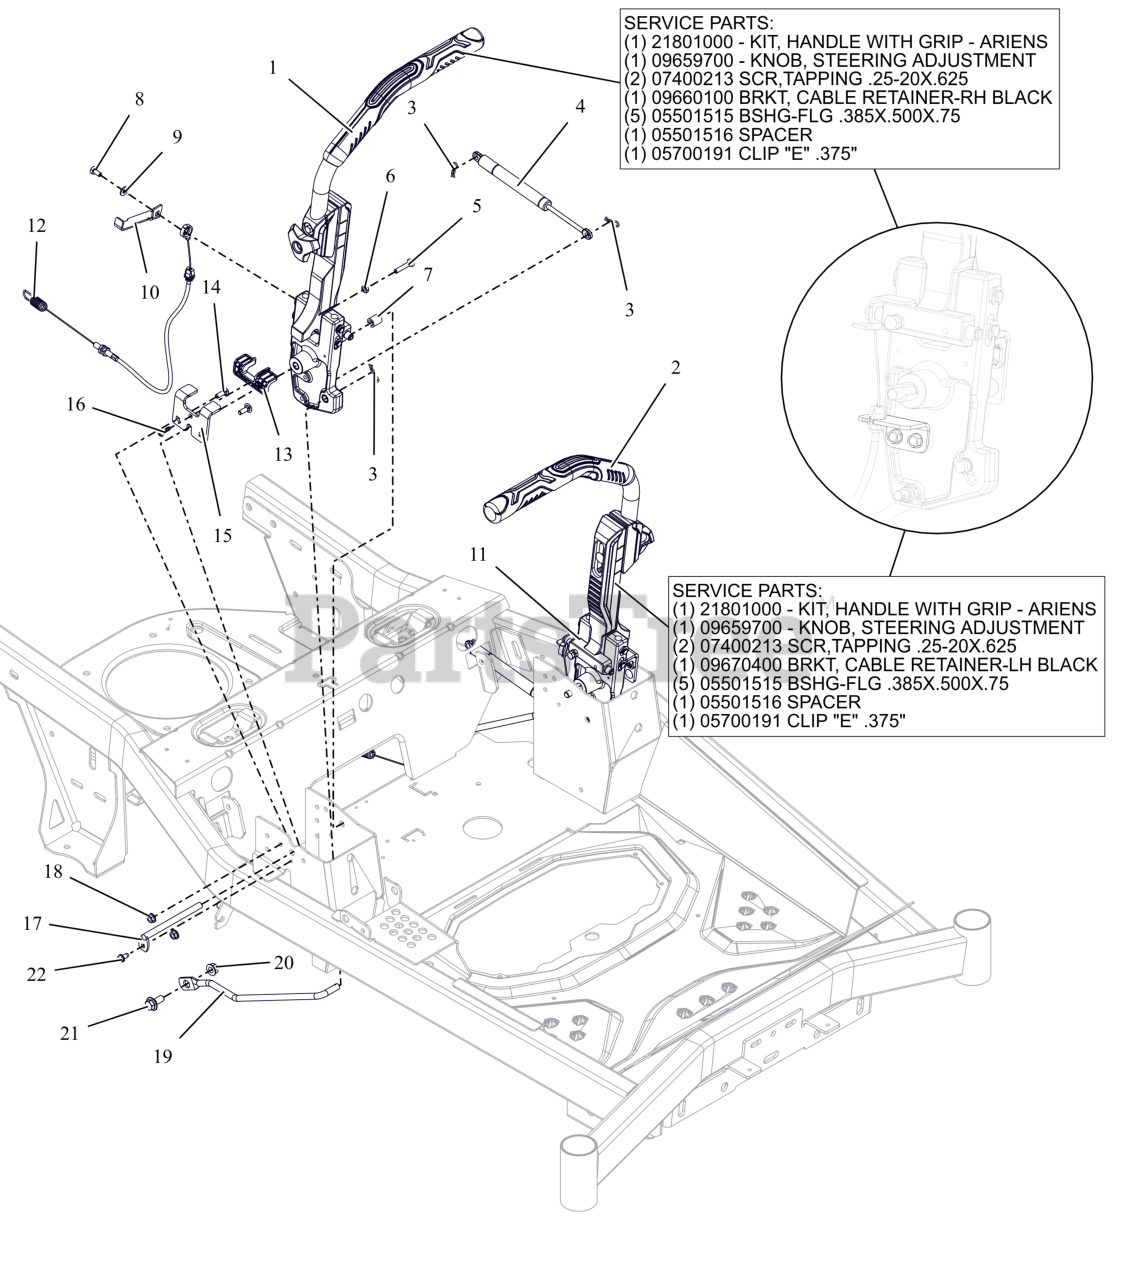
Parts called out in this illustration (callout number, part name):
1	ASM- CONTROLS -RH ARIENS
1	KIT - TUBE WITH GRIP - ARIENS
1	KNOB, STEERING ADJUSTMENT
1	SCREW, TAPPING .25X.20X.625
1	BRKT, CABLE RETAINER -RH BLACK
1	BSHG-FLG .385X500X.75
1	SPACER
1	3/8" E RETAINING RING EXTERNAL
2	ASM- CONTROLS -LH ARIENS
2	KIT - TUBE WITH GRIP - ARIENS
2	KNOB, STEERING ADJUSTMENT
2	SCREW, TAPPING .25X.20X.625
2	BRKT, CABLE RETAINER-LH BLACK
2	BSHG-FLG .385X500X.75
2	SPACER
2	3/8" E RETAINING RING EXTERNAL
3	PIN, HAIR #213 .08X1.19 ZCC
4	DAMPER- STRAIGHT MOUNT
5	BLT, HEX 0.25-20X1.25F GR5 ZCC
6	NUT-JAM .250-20 G2 ZCC
7	SPCR- SNAP-ON 1/2 X 1 1/2
8	BLT, HEX .25-20X.50 G5ZCC EP80
9	WSHR,FLT .281X.625X.065 ZCC
10	BRKT, PARKING BRK ENG R (BLACK)
11	BRKT, PARKING BRK ENG L (BLACK)
12	CABLE- PARK BRAKE
13	STEERING-PLASTIC LINER
14	BLT, RHSN .25-20X.750 G5 ZCC
15	PLATE- BRAKE STOP
16	SCR-TAP 12-14X.75PLSTITE @BLZC
17	PIN- FIXED STEERING PIVOT
18	NUT-LK-CTR-FLG .25-20 ZC120
19	WIREFORM- STEERING LINKAGE
20	NUT-LK-CTR-FLG .375-16 GF ZCC
21	BLT-SHLDR .50X.175 ZCC
22	SCR-TAP .25-20X.50 HWH ZCC
